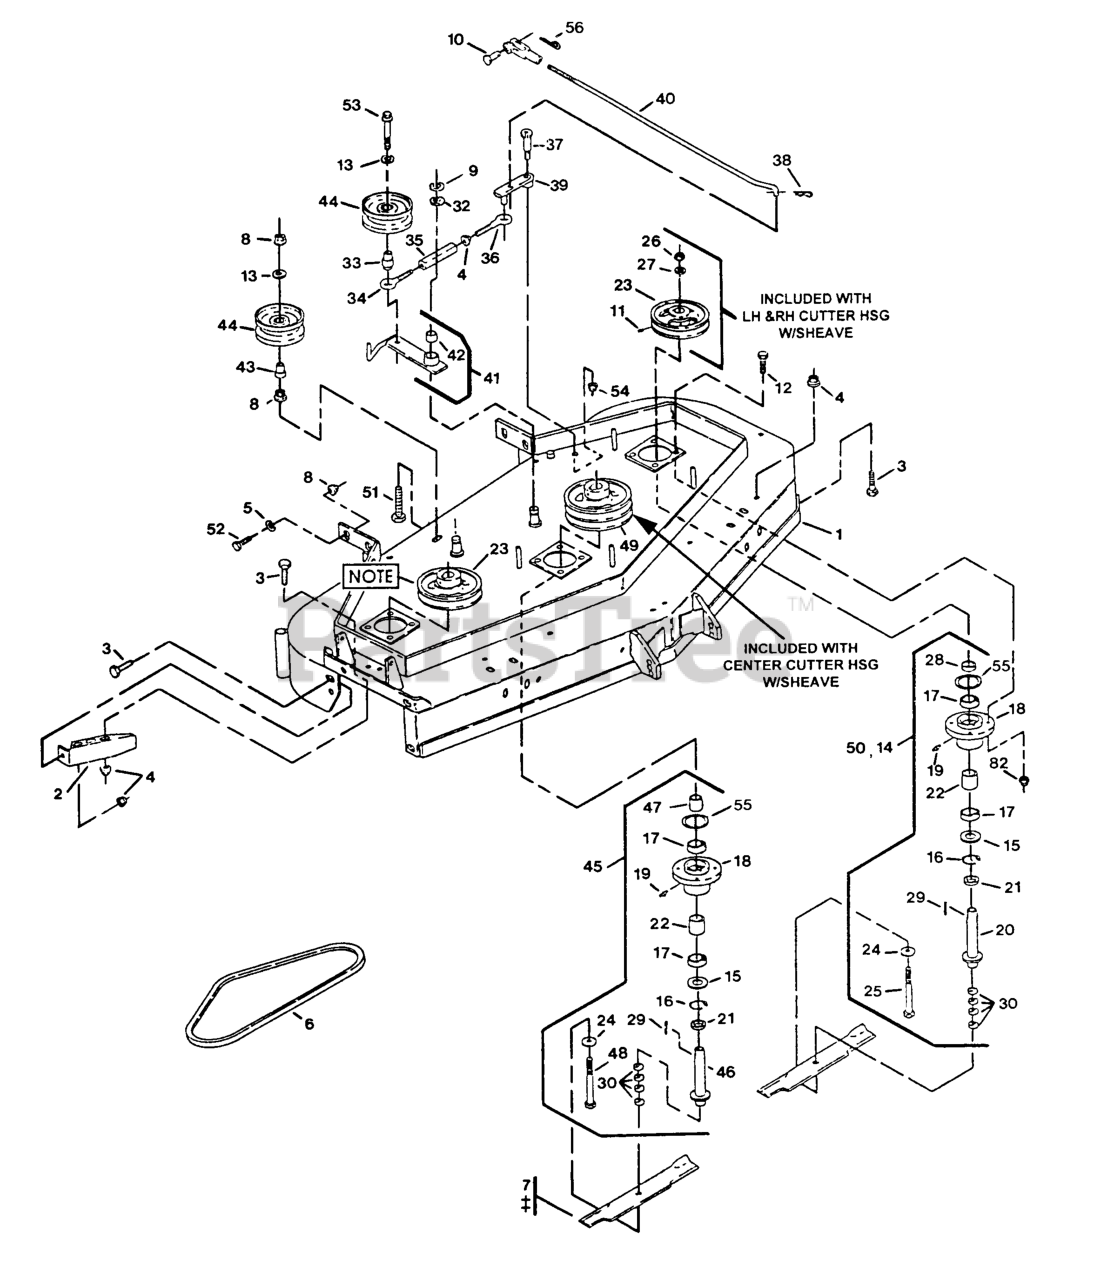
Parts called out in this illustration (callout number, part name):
2	WLD, DISCHARGE BAFFLE
10	PIN-CLEVIS
11	SCREW-SET
14	ASM,HOUSING CUTTER
15	SEAL,DUST
16	RING,SNAP WLDS N5000-244
18	HOUSING,CUTTER
21	SPACER,BEARING &SPINDLE
22	SPACER,BRG/BRG
24	WASHER-SPRING
25	SCREW-CAP, HH
27	WASHER-RETAINER, SHEAVE
31	YOKE-ADJUSTABLE
32	WASHER-SPINDLE
33	BUSHING-ENGAGEMENT
34	EYEBOLT-THREAD, LH
35	BODY-TURNBUCKLE
36	EYEBOLT-THREAD, RH
37	BOLT,SHLDR KSKH
38	PIN-COTTER
42	BEARING,POWDERED METAL
43	BUSHING,IDLER
47	SPACER,BEARING/SHEAVE
48	SCRW,CAP HH 5/8-18X8.5
51	BOLT,TAP HH3/8-16X2-1/4
